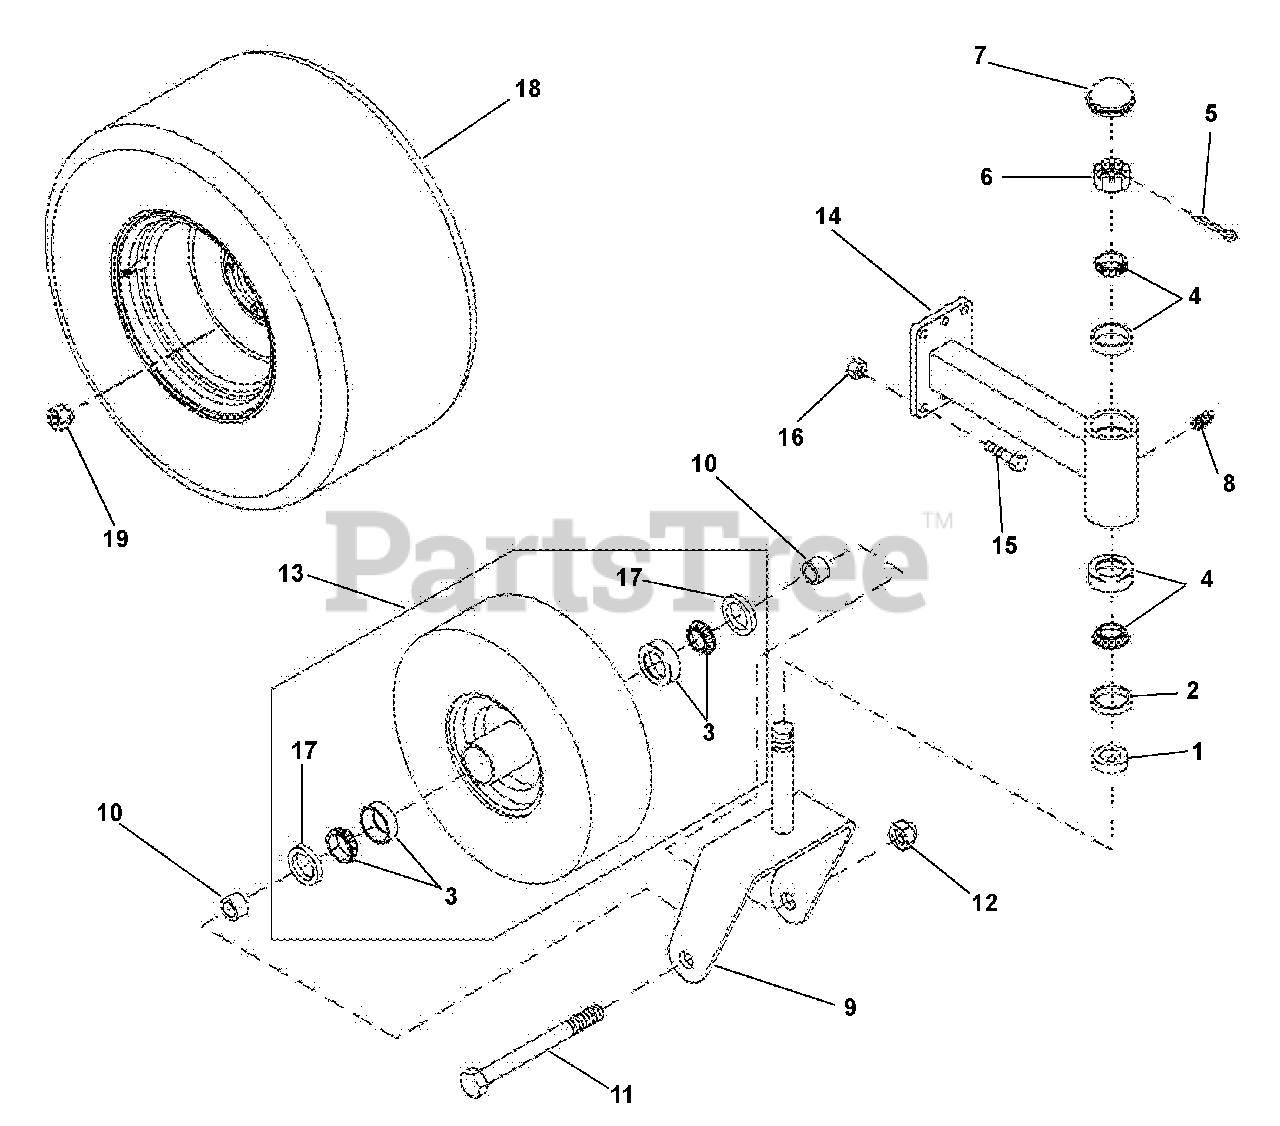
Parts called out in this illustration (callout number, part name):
1	Spacer, Caster Bushing
2	Seal, Wheel Bearing
3	Bearing Assembly, Caster Wheel
4	Spindle Bearing Kit, Cup & Cone
5	Pin, Cotter, DIN 94, 3.2 x 50
6	Nut, Hex, Castellated 1-14
7	Cap, Dust
8	Lubrication Fitting
9	Yoke
10	Spacer, Caster Wheel
11	Bolt, Hex M6 x 1.0 x 12
12	Nut, Jam .31-24
13	Caster, Wheel and Tire Assembly
14	Caster Arm
15	Bolt, Hex, M10 x 1.5 x 25
16	Nut, Locking, Nylon M10-1.5
17	Seal
18	Wheel & Tire Assembly, Rear (994100)
19	Nut, Lug .50-20
